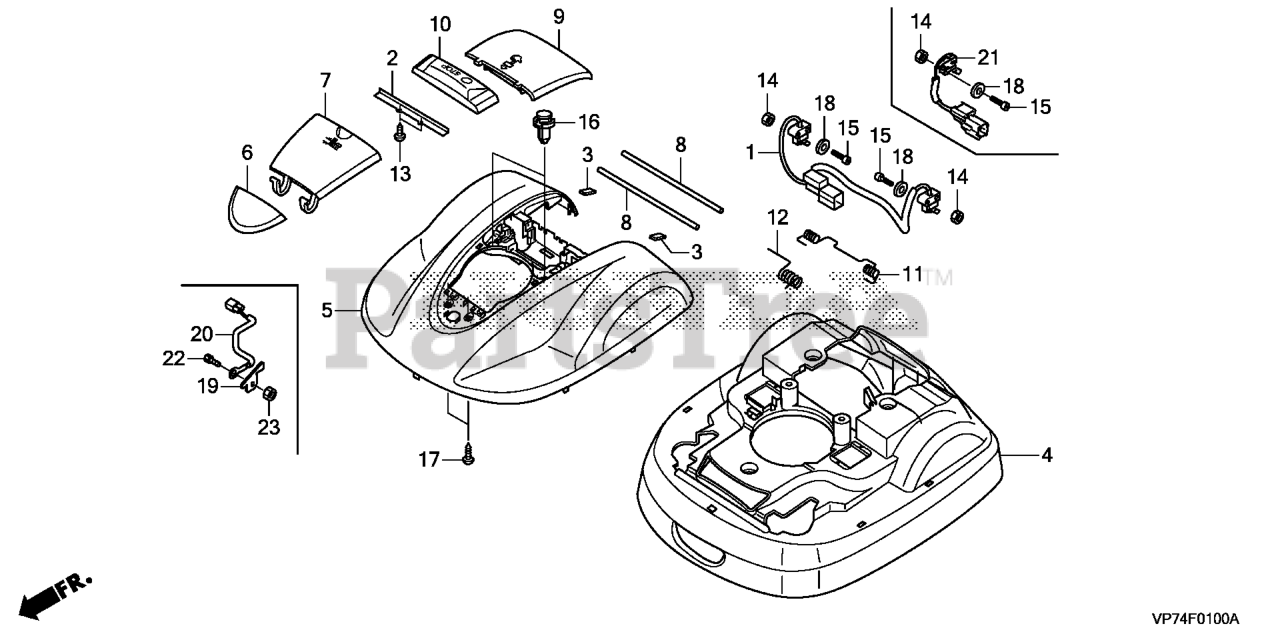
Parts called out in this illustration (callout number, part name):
2	BRACKET, STOP SWITCH
3	CUSHION, COVER
4	COVER, MAIN
5	COVER, TOP
6	COVER, FR.
7	COVER, HEIGHT ADJUSTER
8	SHAFT, STOP SWITCH
9	COVER, CONTROL
10	SWITCH, MANUAL STOP
11	SPRING, CONTROL COVER
12	SPRING, MANUAL STOP SWITCH
13	SCREW, TAPPING (4X8) (PO)
14	NUT, LOCK (3MM)
15	BOLT, SOCKET (3X20)
16	CLIP, BUMPER FACE
17	SCREW, TAPPING (4X12)
18	WASHER, PLAIN (3MM)
19	SOCKET, CHARGE (UPPER)
20	WIRE HARNESS ASSY., TOP
21	SWITCH ASSY., STOP
22	BOLT, SOCKET (3X8)
23	NUT, LOCK (3MM)
